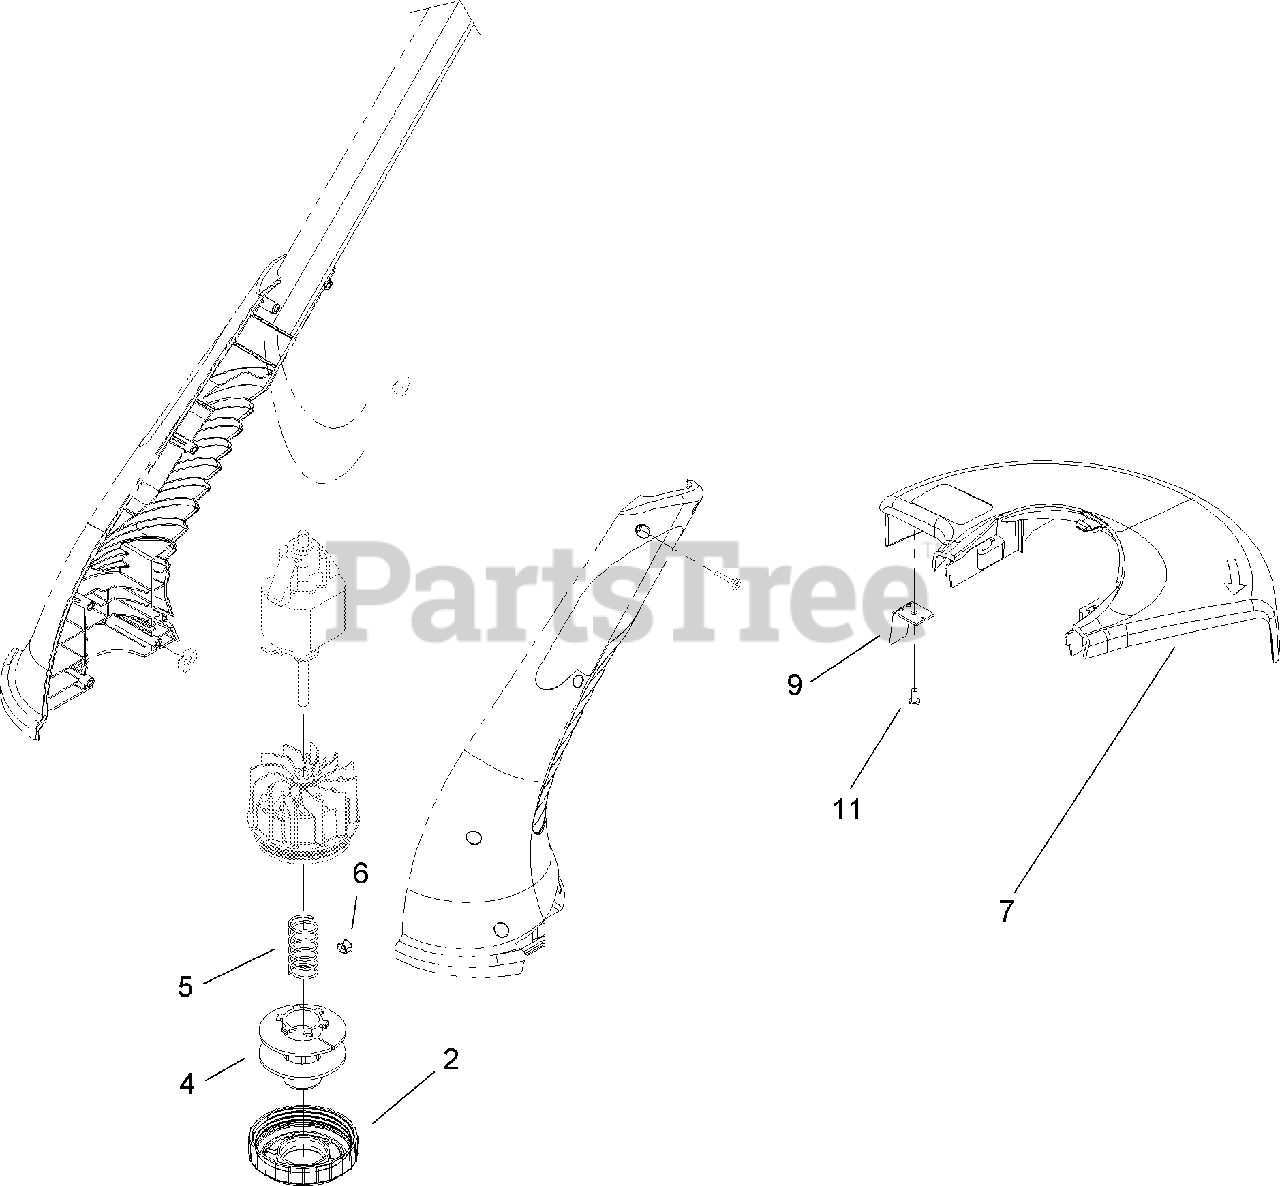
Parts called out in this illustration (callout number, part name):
4	.065 SPOOL ASM
5	Spring-Extension
6	EYELET-GUIDE
7	SHEILD-11 INCH
9	Blade-Cutoff
11	Screw-PPH
